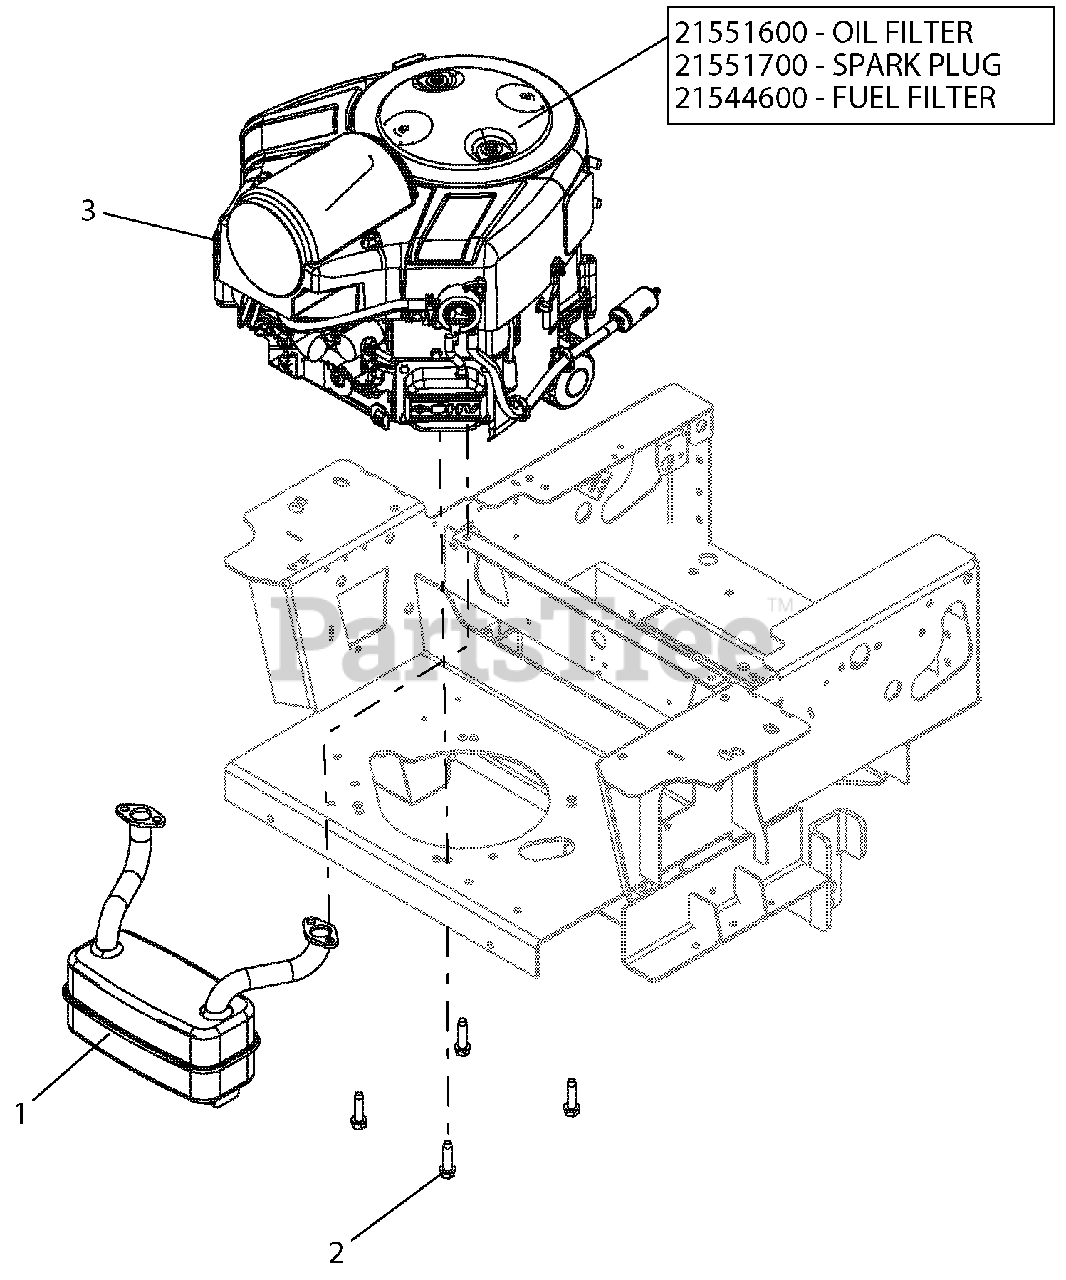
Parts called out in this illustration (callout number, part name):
1	ASM, MUFFLER
2	SCR-TAP .38-16X1.50 HWH TR YZ
3	ENGINE, BRIGGS 724CC VERT SHAFT
3	OIL FILTER
3	SPARK PLUG
3	FUEL FILTER
